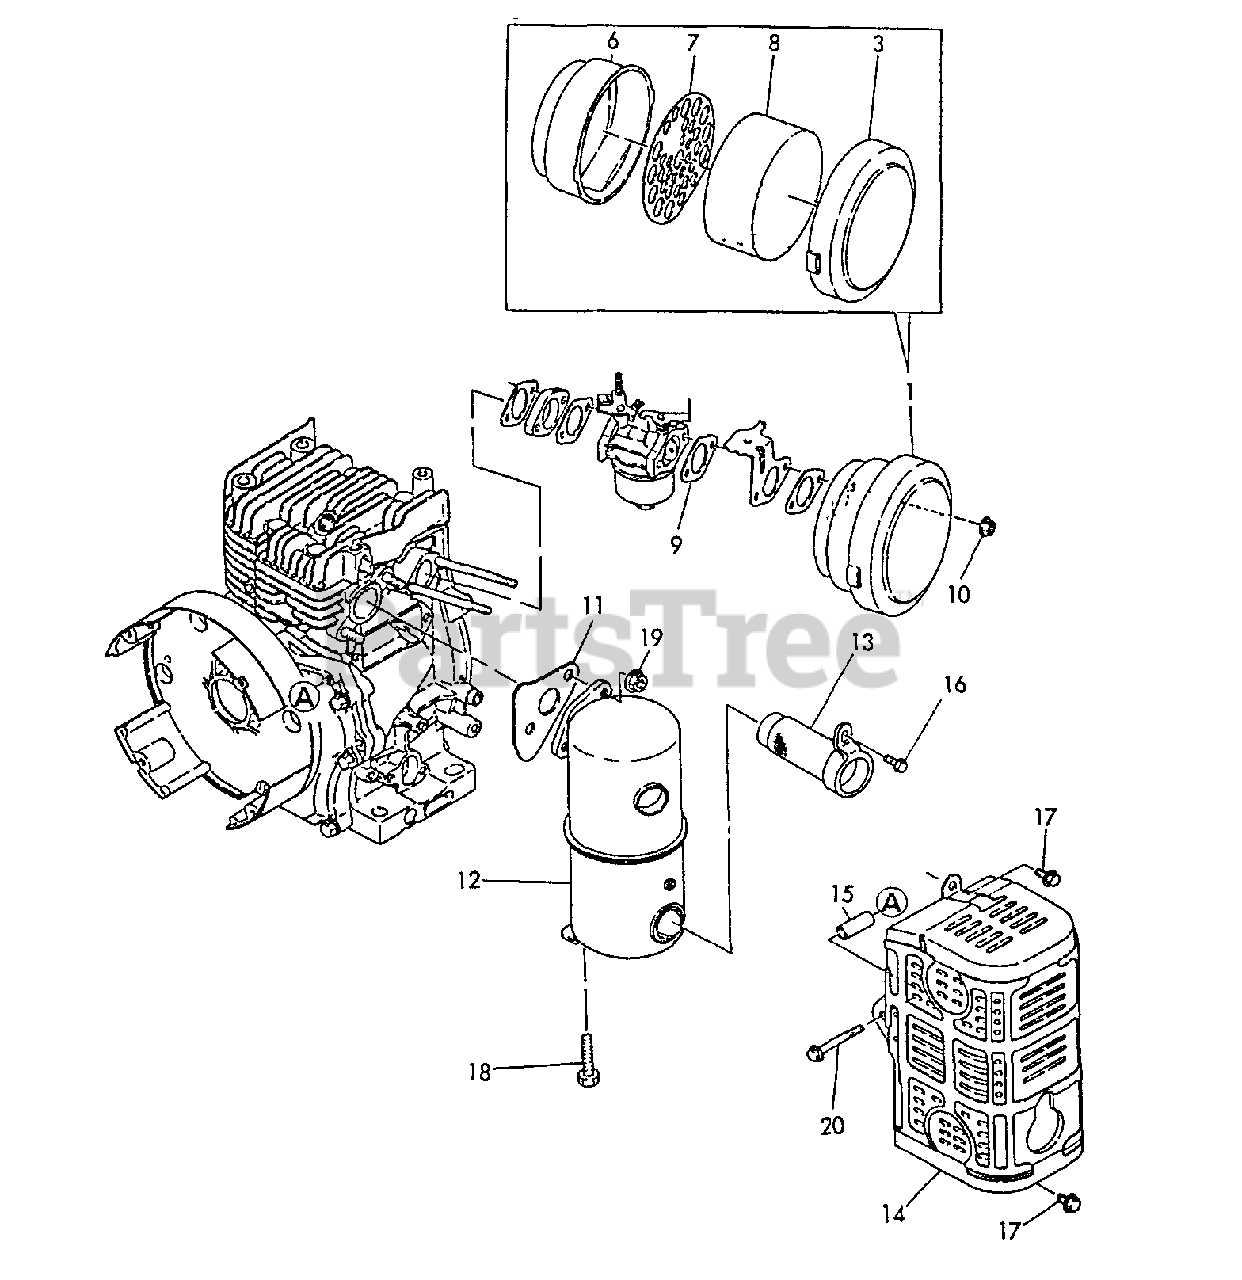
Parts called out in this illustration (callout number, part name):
1	AIR CLEANER ASSY
3	COVER, AIR FILTER
6	CASE, AIR FILTER
7	PLATE, ELEMENT
8	FILTER, AIR
9	GASKET, INTAKE
10	NUT - 6 -- FLANGE
11	GASKET, EXHAUST
12	MUFFLER
13	SCREEN, SPARK ARRESTOR
14	COVER, MUFFLER
15	SPACER
16	BOLT - 6X10 -- PLATED
17	BOLT - 6X16
18	BOLT - 8X30 -- PLATED
19	NUT - 8
20	BOLT - 6X55
